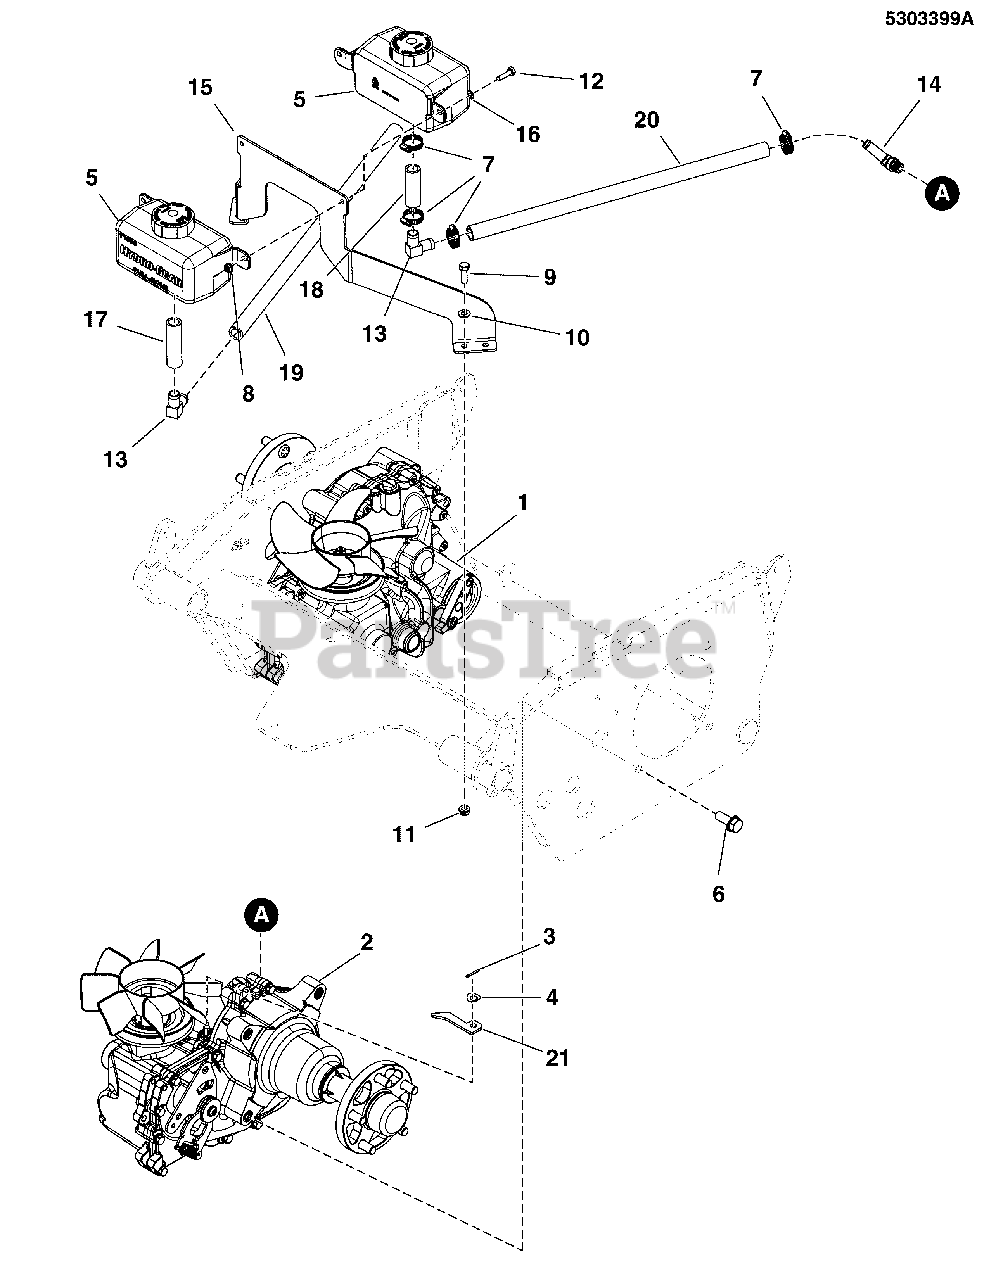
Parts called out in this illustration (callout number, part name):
1	TRANS, ZT-4400, RH,LONG AXLE, 1710-1057R
2	TRANS, ZT-4400, LH,LONG AXLE, 1710-1057L
3	PIN, COTTER, 3/32 X 3/4
4	WASHER,WAVE,M10
5	HYDRO TANK, HYDRO-GEAR 71938, 1 LITER
6	BOLT, 1/2-13 X 1-1/4, SF, PLT W/PATCH
7	CLAMP, #10 HOSE, STAINLESS
8	NUT, 1/4-20 HEX NYLOCK FLANGE
9	BOLT, 5/16-18 X 1 GD5 YZ
10	WASHER, 5/16 SAE
11	NUT, 5/16-18 HEX NYLOCK FLANGE
12	BOLT, 1/4-20 X 1", GD
13	FITTING, 90 DEG, 5/8
14	FITTING 22.5 ELBOW5/8 TUBE-7/8-14 O-RING
15	PLATE, TANK MOUNT, 2100 - BLK
16	WASHER, 1/4 SAE
17	HOSE, 5/8, PUSH-LOCK, 3.00
18	HOSE, 5/8, PUSH-LOCK, 2.50
19	HOSE, 5/8, PUSH-LOCK, 23.00
20	HOSE, 5/8, PUSH-LOCK, 20.00
21	ARM, TRANSMISSION RELEASE, ZT4400
